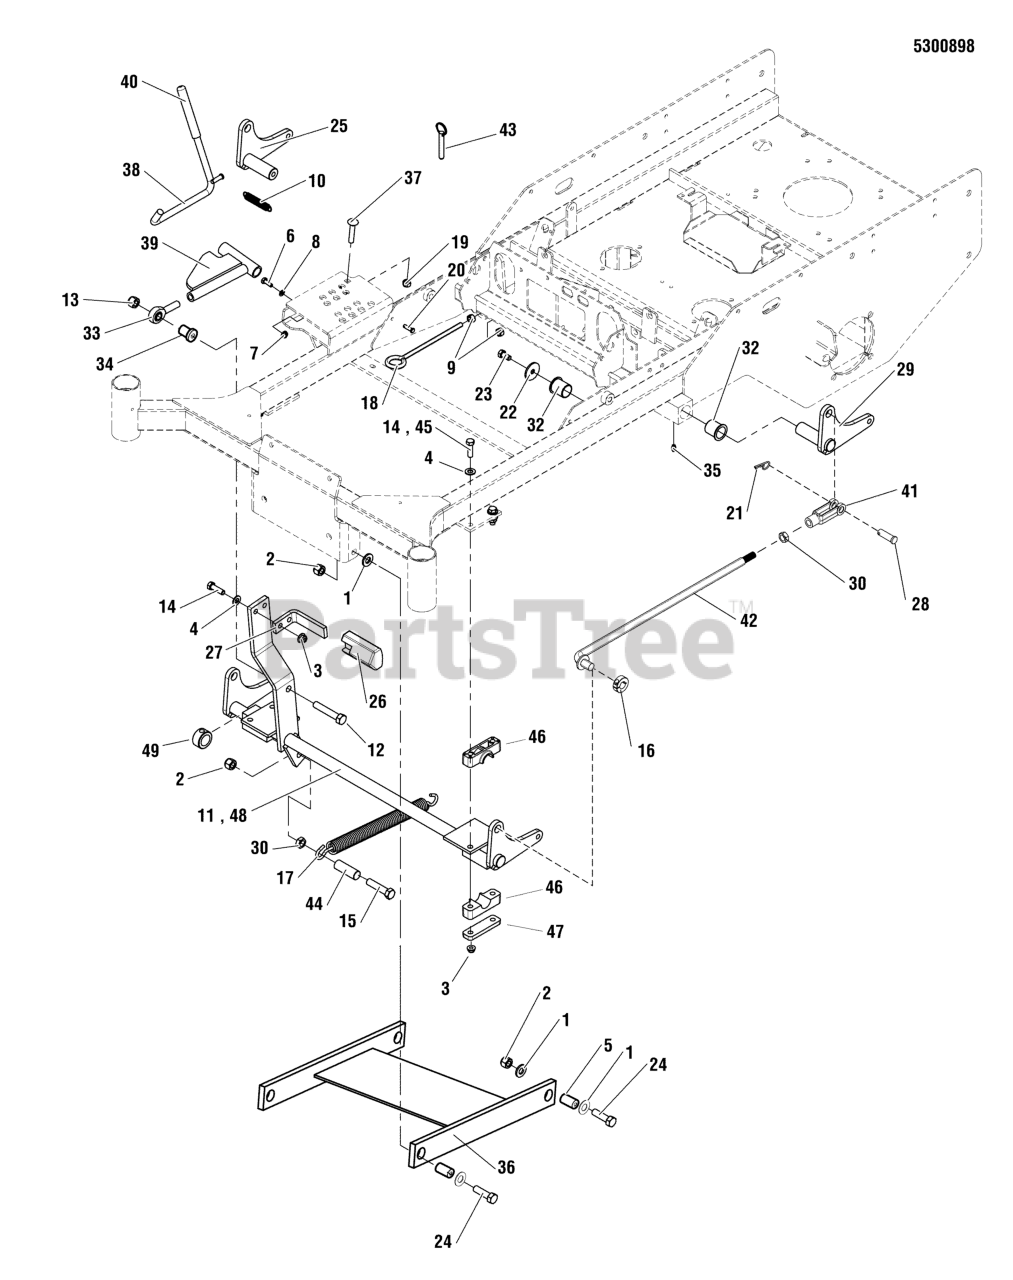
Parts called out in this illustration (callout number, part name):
1	WASHER, 1/2 GD9 YZ
2	NUT, Hex, Nylon Lock, 1/2-20
3	NUT, 3/8-16 HEX NYLOCK FLANGE
4	WASHER, 3/8 SAE
5	INSERT, BEARING
6	BOLT, 1/4-20 X 3/4 GD5 YZ
7	NUT, 1/4-20 HEX SERR. FLANGE
8	WASHER, 1/4 SAE
9	NUT, 3/8-16 HEX
10	SPRING, EXTENSION
11	WELD, SHAFT, DECK LIFT, SNP
12	BOLT, 1/2-13 X 2-3/4 GD5 CZ
13	NUT, Hex Flange, Nylock, 1/2-13
14	BOLT, 3/8-16 X 1-1/4" GD5 CZ
15	BOLT, 1/2-20 X 2-1/4 GD5 CZ
16	COLLAR, 5/8" SPLIT
17	SPRING, DECK LIFT ASSIST
18	EYE BOLT, 3/8-16 X 8", 1" EYE
19	NUT, 3/8-16 HEX SIDE LOCK
20	PIN, CLEVIS, 1/4 X 7/8, PLATED
21	PIN, HAIR, .0915 X 1-7/8
22	WASHER, .390 X 1.50 X .109, YZ
23	BOLT, 3/8-16 X 3/4, GD5, YZ WITH PATCH
24	BOLT, 1/2-20 X 1-3/4" GD8 CZ
25	PIVOT, DECK LIFT WELD - RIGHT - BLK
26	PEDAL, Rubber
27	PEDAL, FOOT - BLK
28	PIN, CLEVIS, 1/2 X 1 1/2, YZP
29	PIVOT, DECK LIFT WELD - LEFT - BLK
30	NUT, 1/2-20 HEX JAM
31	GREASE FITTING, 1/4-28 STRAIGHT
32	BUSHING, 1.00 X 1.13 X 1.38, PLASTIC
33	BALL JOINT, 1/2-20, MALE
34	SPACER, .53 X 1.00 X 1.00
35	GREASE FITTING, 1/4-28 STRAIGHT
36	WELD, DECK STABILIZER - RED
36	WELD, Deck Stabilizer - Blk
37	BOLT, 3/8-16 X 2, CARRIAGE
38	WELD, ROD DECK LIFT - BLK
39	WELD, DECK ADJUST LINK - RED
40	GRIP, FOAM
41	CLEVIS, 1/2-20, STEEL
42	ROD,DECK LIFT ADJUSTMENT
43	PIN, HITCH, 1/2 X 2.00 OAL, YP
44	HOSE, 1/2" PUSH-ON, 1.00"
45	BOLT, 3/8-16 X 2-3/4" GD5 CZ
46	PIVOT BLOCK, PLASTIC
47	PLATE, PIVOT BLOCK SUPPORT - BLK
48	WELD, DECK LIFT SHAFT
49	COLLAR, 1" DOUBLE SPLIT
